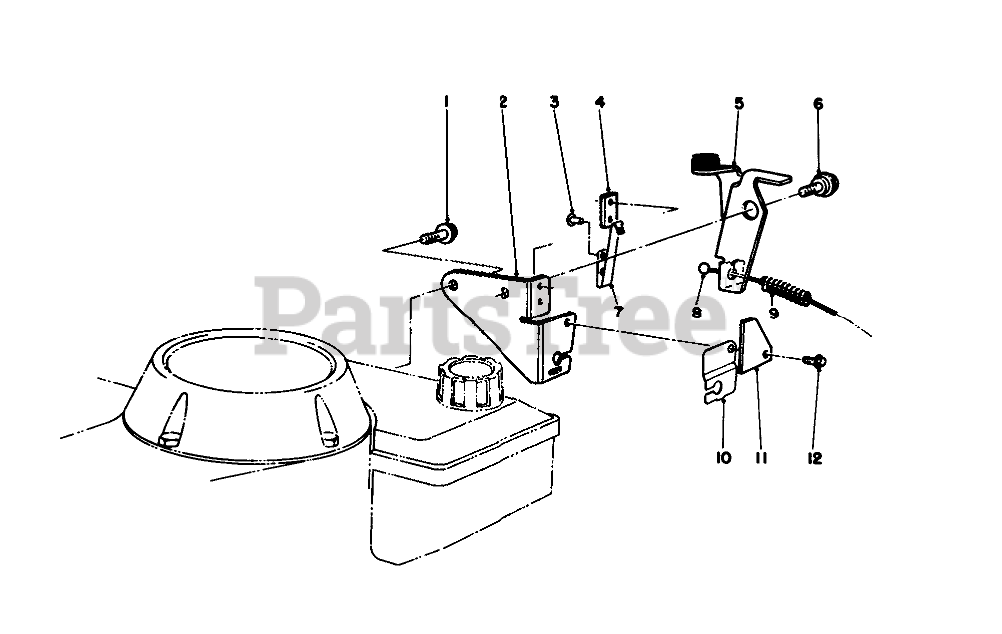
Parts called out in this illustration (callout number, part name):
1	THO FORM SCREW M6 X 1
2	Plate-Mounting
3	RIVET-PLASTIC
4	Strap-Insulation
5	BRAKE PLATE ASM
6	Screw-Shoulder
7	STRAP-GROUND
8	BRAKE CABLE
9	SPRING-COMPRESSION
10	CABLE CLAMP
11	STOP-GROUND STRAP
12	SCREW
